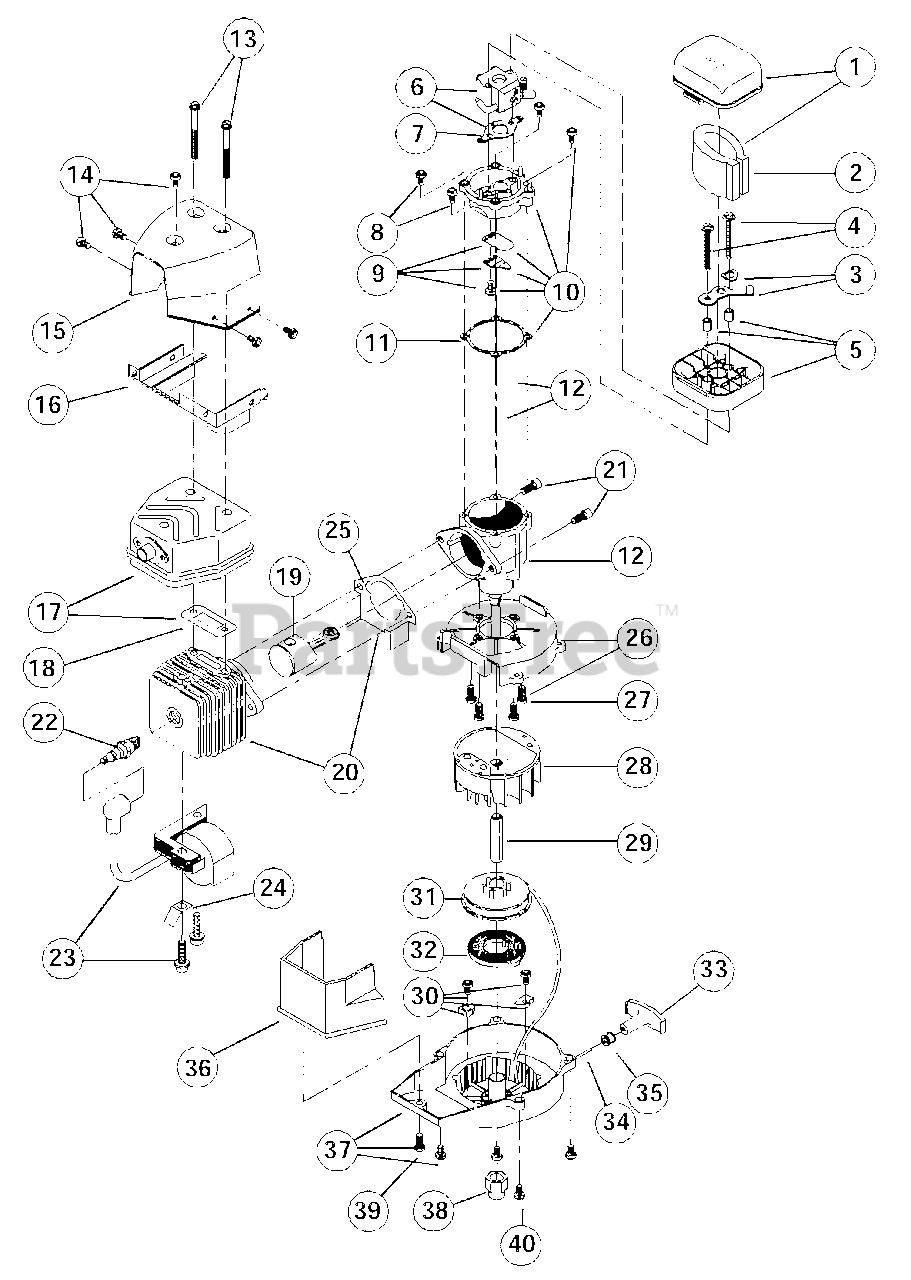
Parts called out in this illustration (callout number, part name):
1	Air Cleaner Cover Assembly
2	Air Cleaner Filter
3	Choke Lever Assembly
4	Mounting Bolt Assembly
5	Air Cleaner Base
6	Carburetor Assembly
7	Carburetor Gasket (10 pack)
8	Reed Plate Mounting Screw
9	Reed Assembly
10	Complete Reed Plate Assembly
11	Reed Plate Gasket
12	Crankcase Service Assembly
13	Muffler Mounting Bolt
14	Mounting Screw Assembly
15	Upper Heat Shield
16	Lower Heat Shield
17	Muffler Assembly
18	Exhaust Gasket (10 pack)
19	Piston and Rod Assembly
20	Cylinder Assembly
21	Cylinder Bolt
22	Spark Plug
23	Module Assembly
24	Ground Tab
25	Cylinder Gasket
26	Shroud Assembly
27	Shroud Screw
28	Flywheel Assembly
30	Pulley Retainer Assembly
31	Recoil Pulley Assembly
32	Recoil Spring
33	Pull Handle
35	Rope Guide
36	Shroud Extension
37	Starter Housing Assembly
38	Crankshaft Extension
39	Shroud Extension Screw
40	Housing Screw
